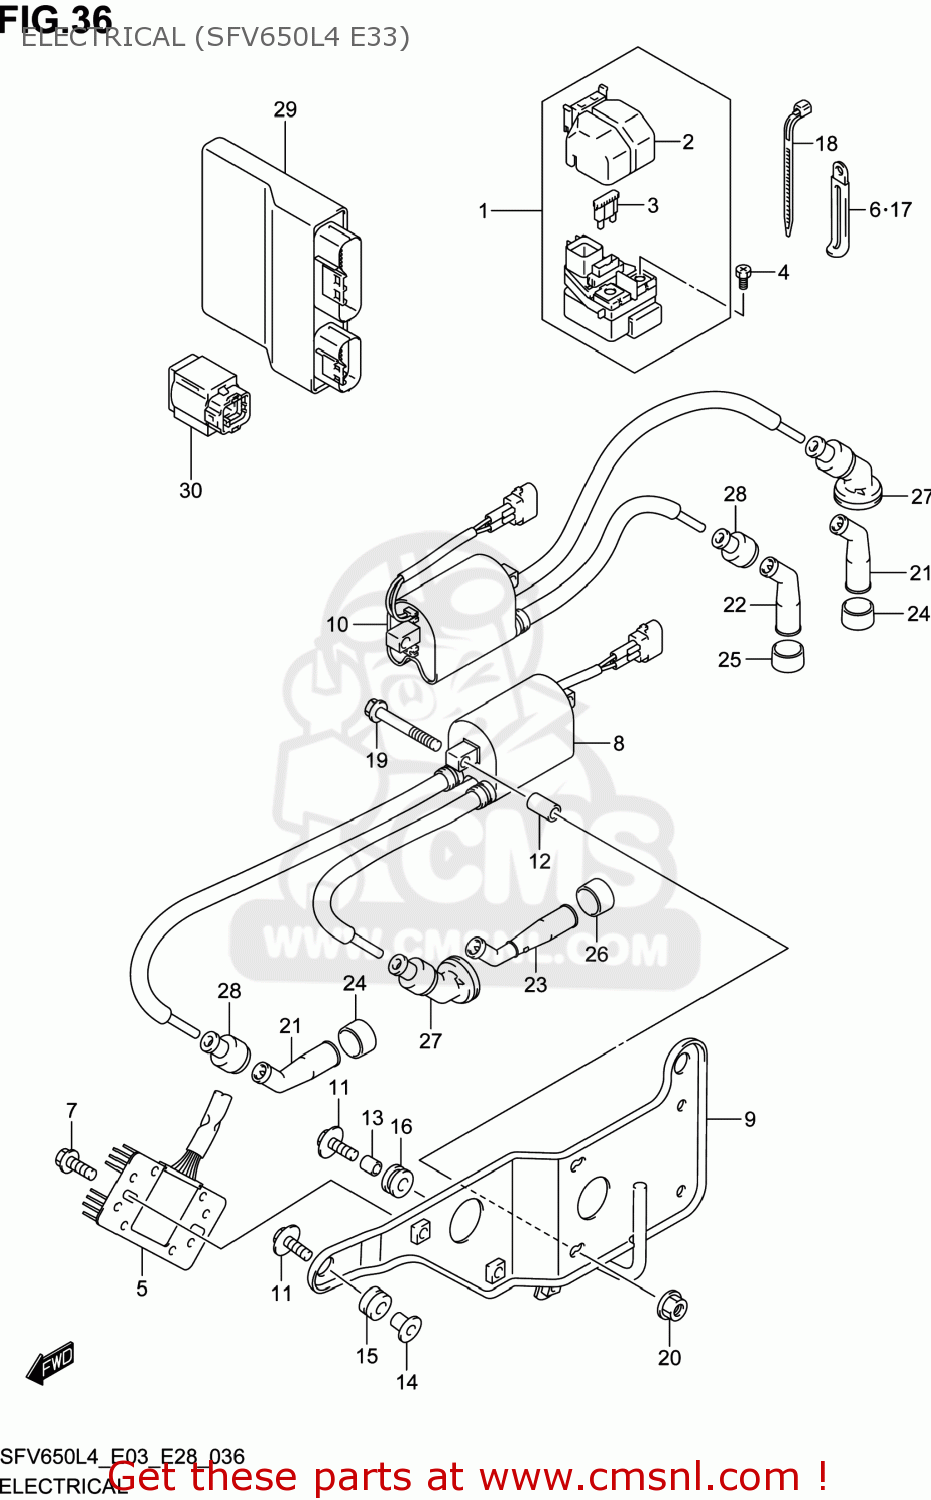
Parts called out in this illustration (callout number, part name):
1	RELAY ASSY,STARTING MOTOR
2	COVER
3	FUSE(30A)
4	SCREW(6X8)
5	RECTIFIER ASSY
6	CLAMP(L:45)
7	SCREW
8	COIL ASSY,IGNITION FR
9	BRACKET,IGNITION COIL RR
10	COIL ASSY,IGNITION RR
11	BOLT(6X20)
12	SPACER(6.4X10X18)
13	SPACER(6.5X9X9)
14	SPACER(6.2X8.4X10.9)
15	CUSHION
16	CUSHION
17	CLAMP(L:80)
18	CLAMP(L:165)
19	BOLT
20	NUT
21	CAP ASSY,SPARK PLUG
22	CAP ASSY,SPARK PLUG
23	CAP ASSY,SPARK PLUG
24	SEAL,SPARK PLUG
25	SEAL,SPARK PLUG
26	SEAL,SPARK PLUG
27	SEAL,HIGH TENSION CORD CTR
28	SEAL,HIGH TENSION CORD
29	CONTROL UNIT,FI
30	SENSOR ASSY,FUEL CUT
